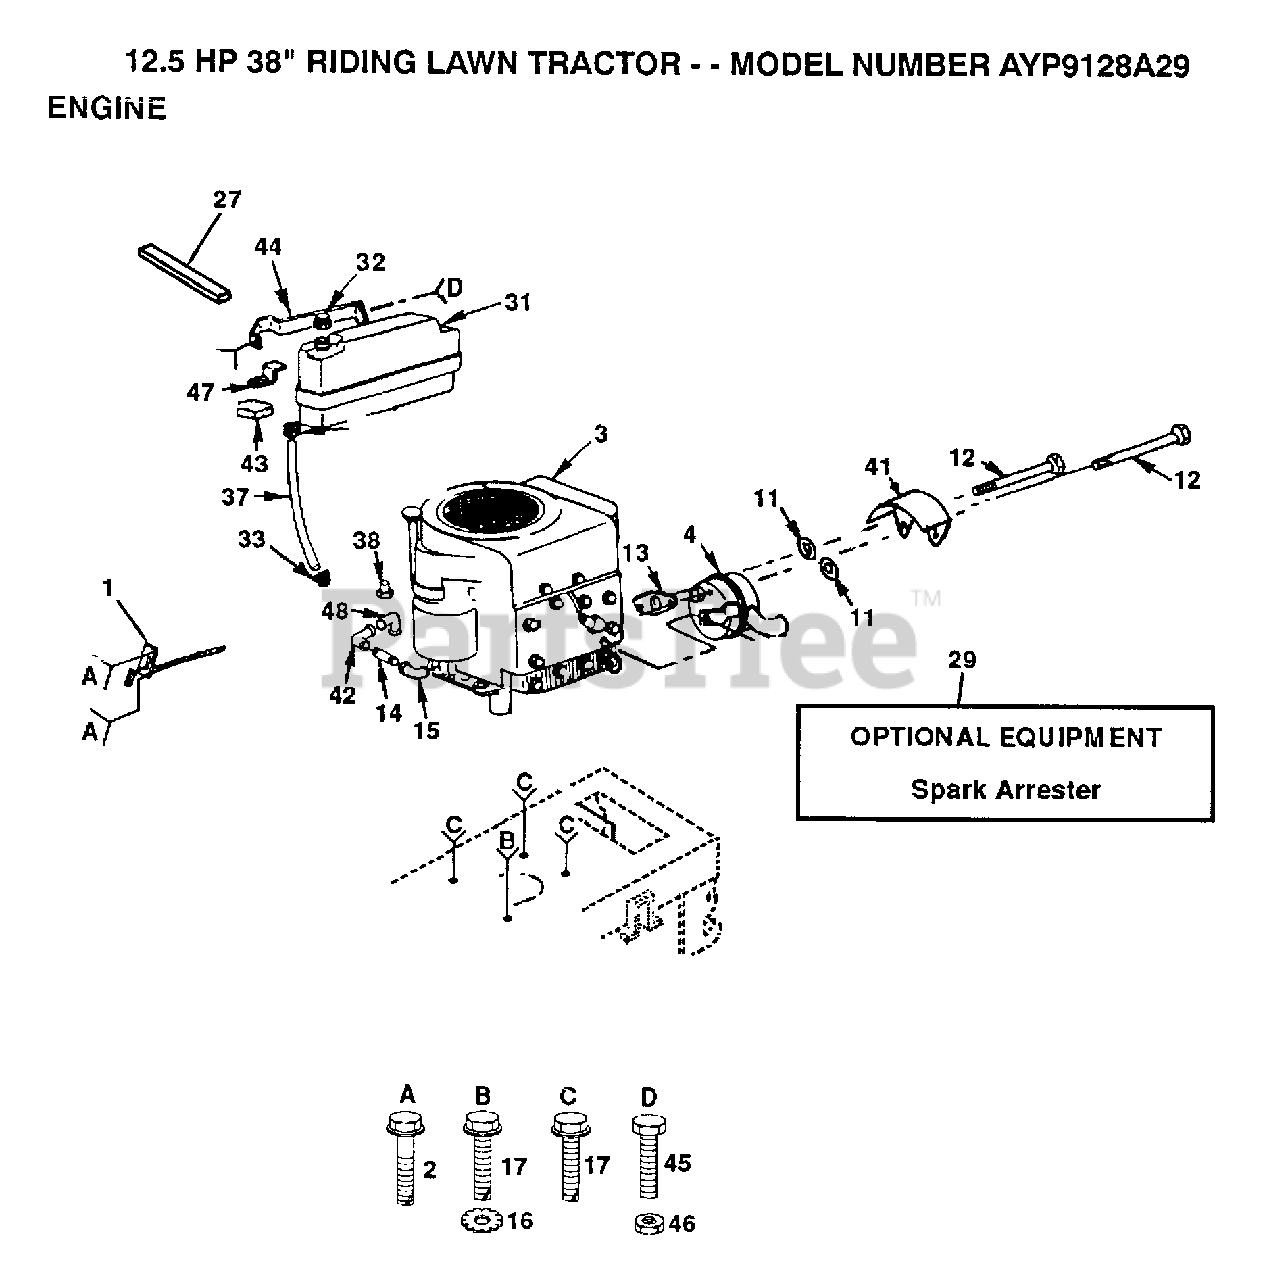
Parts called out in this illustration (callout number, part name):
1	THROTTLE CONTROL
2	SCREW LT
4	MUFFLER
12	BOLT
14	PIPE NIPPLE
15	STREET ELBOW LT
16	LOCKWASHER
17	SCREW
27	FOAM-STRIP LT
31	FUEL TANK
33	HOSE CLAMP
41	HEAT SHIELD
42	STREET ELBOW LT
43	PAD-SPACER T
44	SUPT TANK FUEL
45	BOLT
47	BRACE-TANK LT
48	ELBOW
